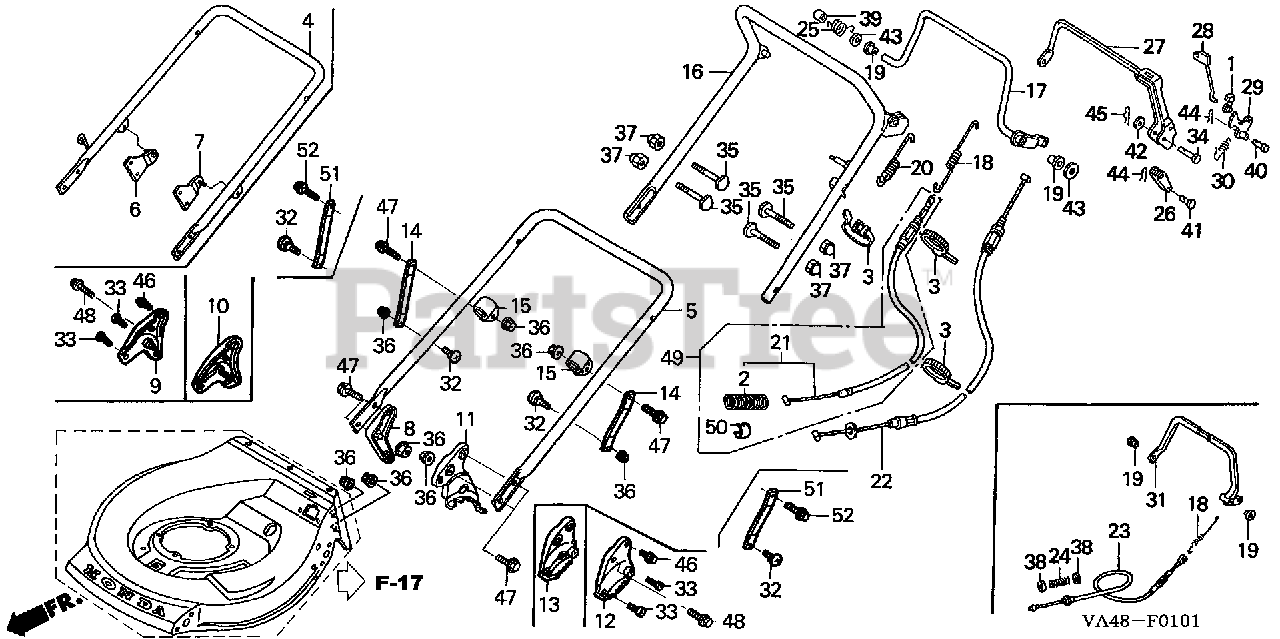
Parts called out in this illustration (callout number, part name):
3	TIE, CABLE (157.5MM)
4	PIPE, HANDLE (LOWER) *NH105* (MAT BLACK)
5	PIPE, HANDLE (LOWER) *NH105* (MAT BLACK)
6	STAY, R. HANDLE SUPPORT *NH105* (MAT BLACK)
7	STAY, L. HANDLE SUPPORT *NH105* (MAT BLACK)
8	STAY, R. HANDLE *NH190M* (VINTAGE GRAY METALLIC)
9	STAY, R. HANDLE
11	STAY, L. HANDLE *NH190M* (VINTAGE GRAY METALLIC)
12	STAY, L. HANDLE
14	PLATE, HANDLE SUPPORT *NH105* (MAT BLACK)
15	HANGER, HANDLE SUPPORT
16	PIPE, HANDLE (UPPER) *NH105* (MAT BLACK)
18	SPRING, CLUTCH
19	BUSH, CLUTCH LEVER
23	CABLE, BRAKE
24	SPRING B, BRAKE
25	SPRING, R. STOP RETURN
31	LEVER, BRAKE *NH105* (MAT BLACK)
32	BOLT, SPECIAL (9X15)
33	BOLT, FLANGE (8X16) Use from Engine SN 1000016.
34	PIN, CLUTCH LEVER
35	BOLT, HANDLE HOLDER (8X36)
36	NUT, SELF-LOCK (8MM)
37	NUT, CAP (8MM)
38	WASHER, SPECIAL (6MM)
39	COLLAR (8X11X13.5)
43	WASHER, PLAIN (8MM)
45	PIN, LOCK (8MM)
46	BOLT, FLANGE (8X16) Use from Engine SN 1000016.
46	BOLT, FLANGE (8X18)
47	BOLT, FLANGE (8X16) Use from Engine SN 1000016.
47	BOLT, FLANGE (8X16)
48	BOLT, FLANGE (8X40)
48	BOLT, FLANGE (8X45)
51	PLATE, HANDLE SUPPORT *NH105* (MAT BLACK)
52	BOLT, FLANGE (8X16)
